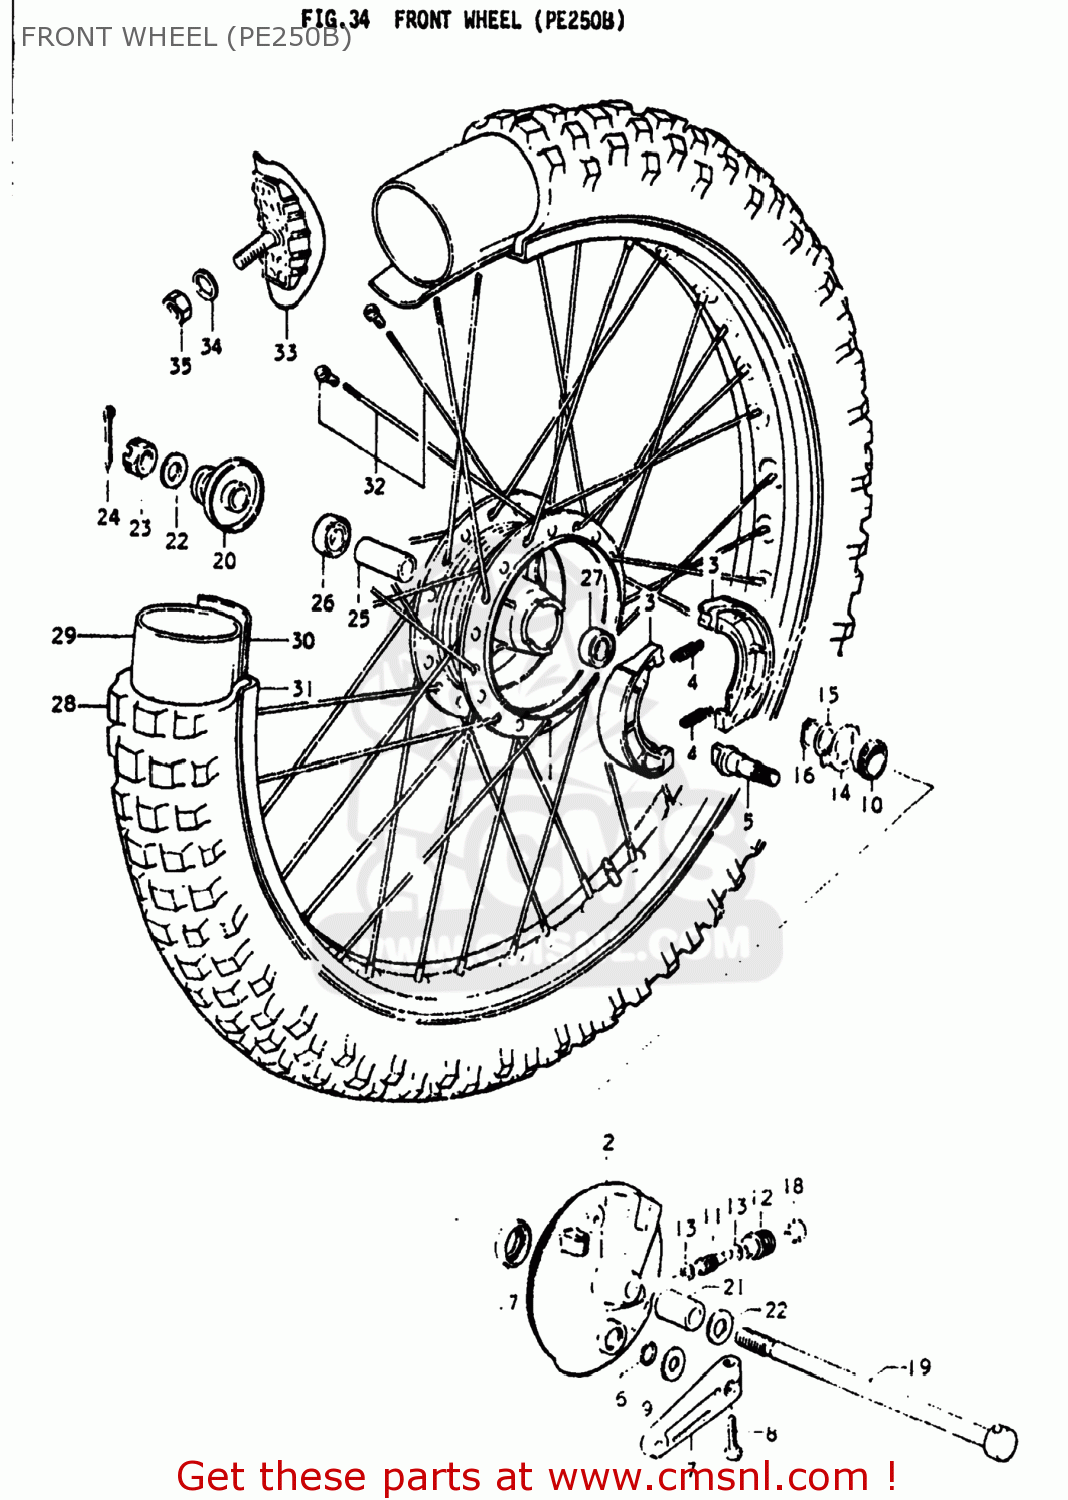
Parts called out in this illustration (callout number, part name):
1	HUB,FRONT
2	PANEL,FRONT HUB
3	SHOE,BRAKE
4	SPRING
5	CAM,FRONT BRAKE
6	O-RING,BOSS
7	LEVER,FRONT BRAKE CAM
8	BOLT
9	WASHER (15X24X1.6)
10	GEAR,SPEEDOMETER
11	PINION,SPEEDOMETER
12	PINION,SPEEDOMETER
13	WASHER (5.1X9X0.4)
14	DRIVER,SPEEDOMETER GEAR
15	WASHER(22.5X27X1)
16	CIRCLIP
17	OIL SEAL
18	SEAL,OIL(6X10X3)
19	AXLE,REAR
20	SPACER,FRONT AXLE,RIGHT
21	SPACER
22	WASHER
23	NUT, REAR AXLE
24	COTTER PIN
25	SPACER (12.6X19X52)
26	BEARING
27	BEARING, LH
28	TIRE,FRONT
29	TUBE
30	PROTECTOR,WHEEL,INNER
31	RIM,FRONT WHEEL
32	SPOKE SET,FRONT
33	STOPPER,BEAD
34	WASHER
35	NUT
